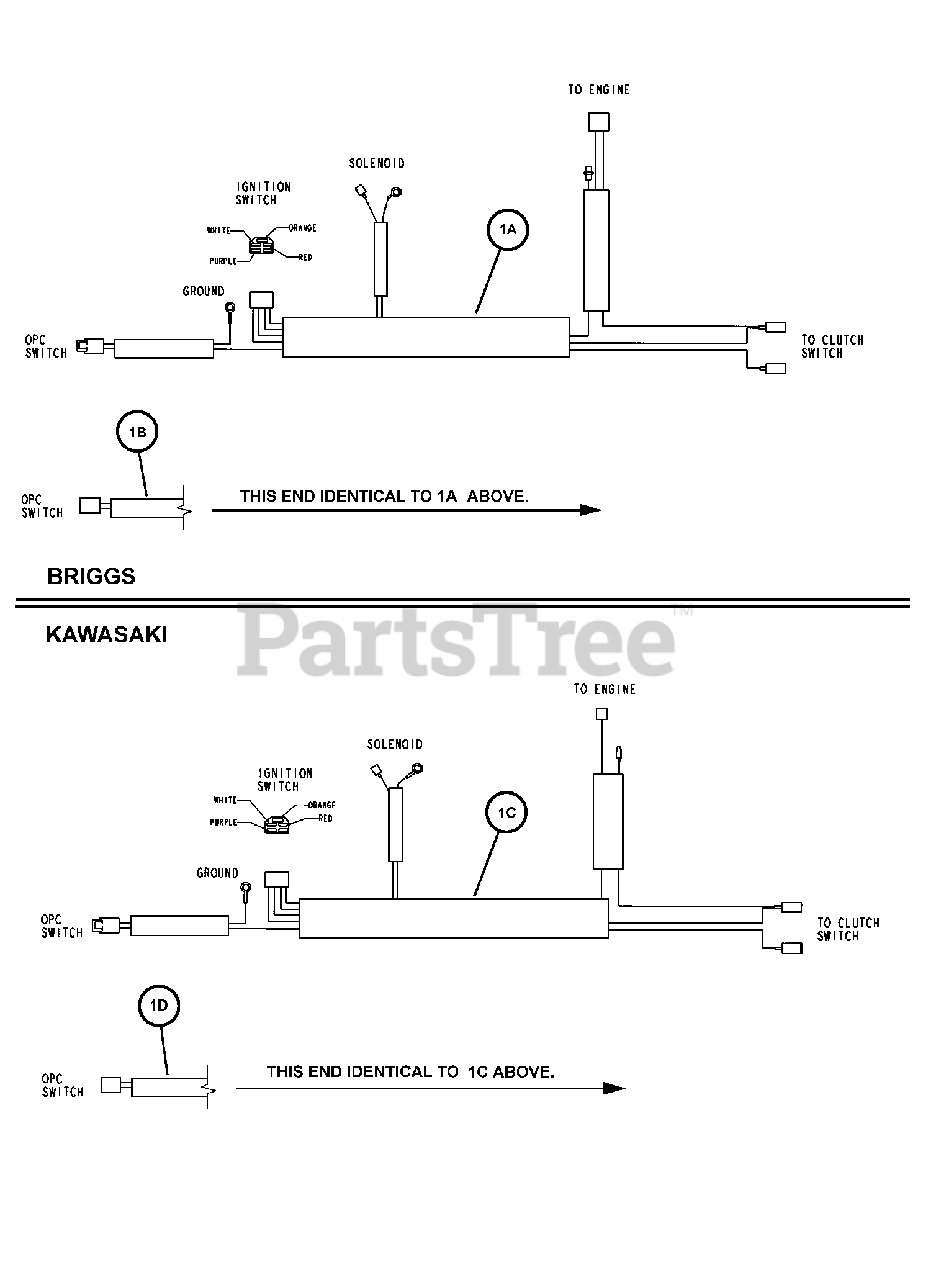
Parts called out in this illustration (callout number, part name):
1A	WIRE HARNESS, Briggs
1B	WIRE HARNESS, Briggs
1C	WIRE HARNESS, Kawasaki
1D	WIRE HARNESS, Kawasaki
